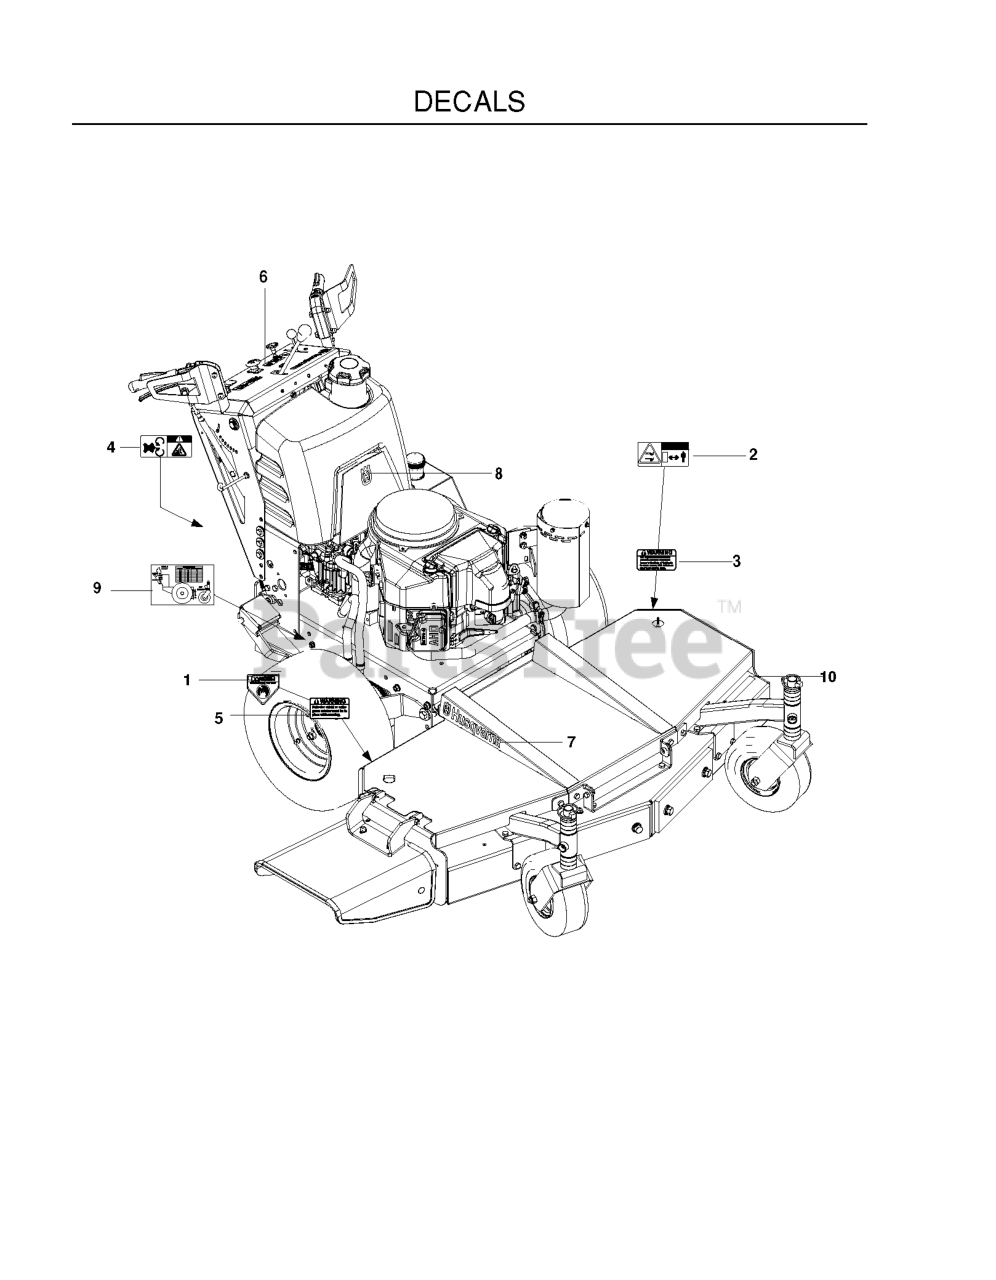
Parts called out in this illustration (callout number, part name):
1	DECAL, CPSC
2	DECAL, EURO SEVERING
3	DECAL, PROP. 65
4	DECAL, BELT DRIVE
5	DECAL, CAUTION
6	DECAL, INST PANEL
7	RP.DECAL.BADGE.170MM.TEXTLOGO
8	DECAL.AUGER.HUSQ.CROWN.SNOW
9	DECAL, HEIGHT OF CUT
10	DECAL, WH3616
